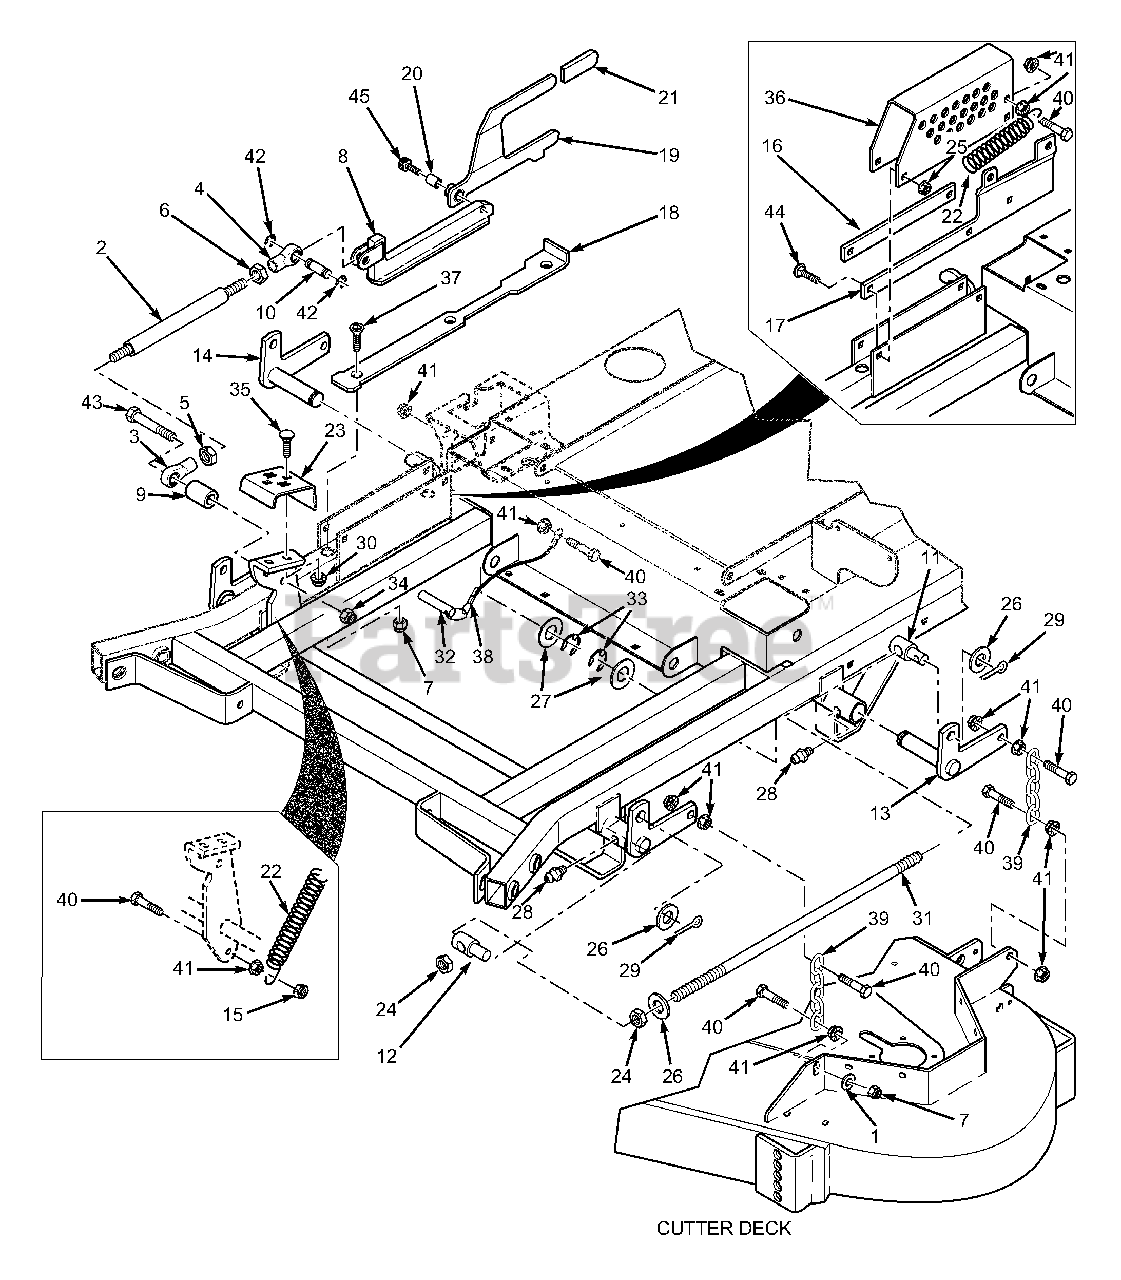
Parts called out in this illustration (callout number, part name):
1	Flatwasher, 3/8"
2	Link, Deck Lift
3	Rod End, Female - 1/2-20 RH
4	Rod End, Female - 1/2-20 LH
5	Nut, Jam 1/2-20 RH
6	Nut, Jam 1/2-20 LH
7	Nut, 3/8-16 Elastic Stop
8	Slide Weldment, Height Adjustment
9	Spacer, Decklift Pedal
10	Pin, Decklift
11	Swivel Joint, LH
12	Swivel Joint, RH
13	Bellcrank Weldment, LH Rear
14	Bellcrank Weldment, RH Rear
15	Locknut, 3/8-16 Center Lock
16	Guide, Short
17	Guide, Long
18	Lockplate, Decklift
19	Deck Latch
20	Bushing, .502 ID.
21	Grip, Deck Latch
22	Spring, Helper (61" & 72" Cutter Decks Only)
23	Foot Pedal, Height Adjustment
24	Nut, Hex 5/8-11
25	Nut, Hex Serrated Flange 5/16-18
26	Flatwasher, 5/8" (.656 x 1.312 x .095)
27	Flatwasher, 1" (1.062 x 1.50 x .048)
28	Grease Fitting
29	Cotter Pin, 3/16 x 1"
30	Nut, Hex Elastic Stop 5/16-18
31	Stud, 5/8-11 x 22.0"
32	Ring Pin, 1/2 x 3.30"
33	Ring, Retaining 1" External "E"
34	Nut, Hex Elastic Stop 1/2-13
35	Bolt, Carriage 3/8-16 x 1-1/4"
36	Bracket, Cutting Height Adjustment
37	Screw, Cap 5/16-18 x 3" FHHS
38	Lanyard, Deck Height Pin
39	Chain
40	Bolt, Hex Head 3/8-16 x 1-1/2"
41	Nut, Hex Serrated Flange 3/8-16
42	Ring, Retaining 1/2" External "E"
43	Bolt, Hex Head 1/2-13 x 3"
44	Bolt, Carriage 5/16-18 x 1"
45	Bolt, Shoulder 1/2 x 3/4"
